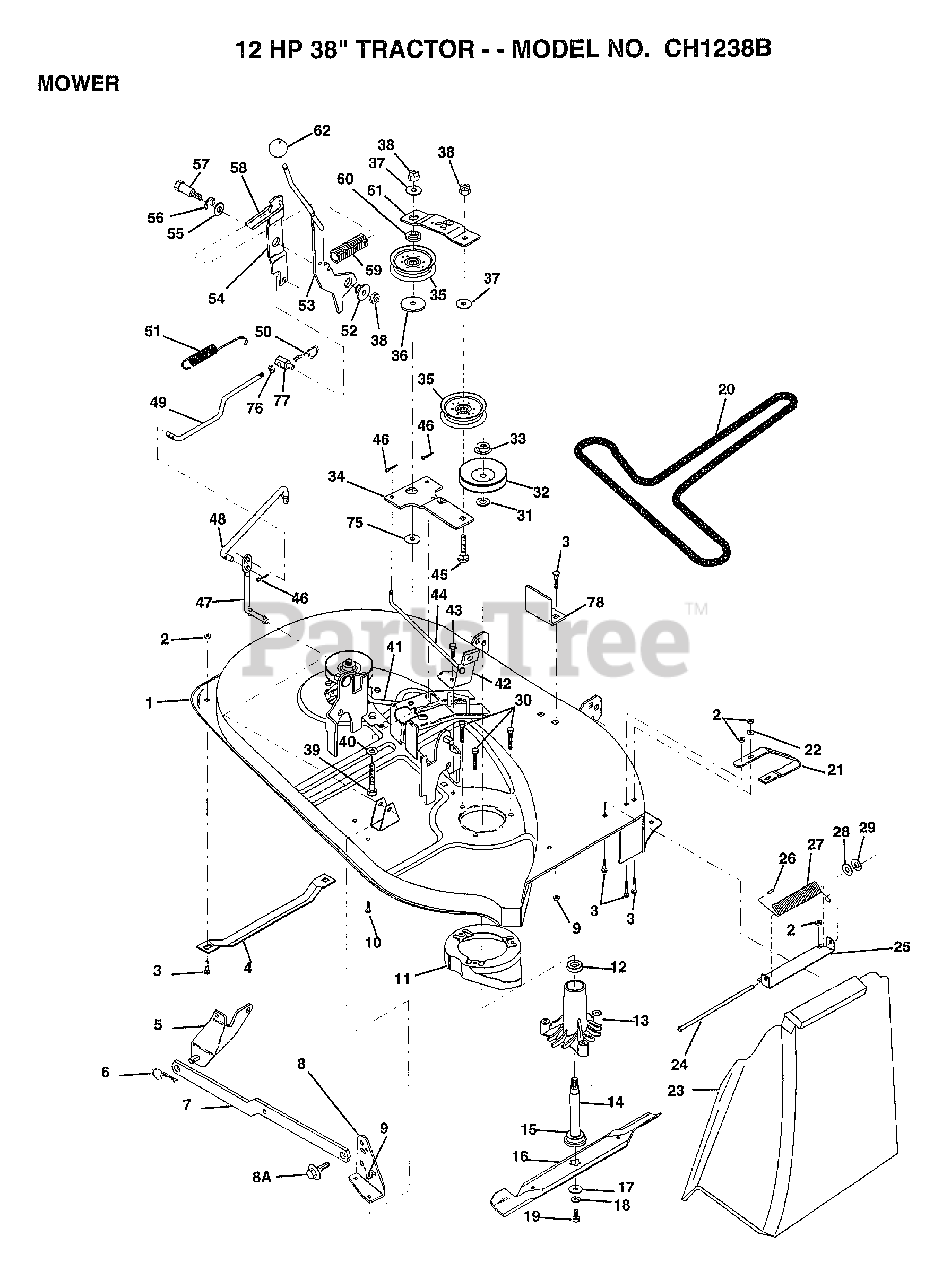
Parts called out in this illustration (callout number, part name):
2	NUT
3	BOLT
4	RUNNER-LH M
5	BRKT ASM SWAY BAR
8	BRKT DECK SW BAR
8A	BOLT SHD 5/16-18
9	NUT
10	BOLT
12	BEARING
13	HSG ASM MANDREL
15	BEARING.BALL
16	"BLADE.38""V.MULCH"
17	WASHER.HARD.BLADE
19	BLADE BOLT
20	BELT-V.88.12.MW
21	RUNNER RH
22	WASHER M
23	DEFLECTOR-SHLD T
24	ROD-HINGE T
25	BRKT DEFLECTOR
26	CAP-SLEEVE LT
27	SPRING TORSION
28	WASHER
29	NUT PUSH M
31	WASHER
34	IDLER ARM ASSY
35	FLAT IDLER PULLEY
36	SPACER RETAINER
37	WASHER GT
38	NUT
39	BOLT
40	WASHER GT
41	BRAKE ROD LH
42	BRAKE ASM
43	SCREW
44	BRAKE ROD RH
45	BOLT
47	PIVOT ROD
48	CLUTCH ROD SECOND
49	ROD CLUTCH 38/42
50	RETAINER M
51	RETURN SPRING
52	BUSHING
54	CLUTCH ARM SECOND
55	WASHER
56	RING
57	SHOULDER BOLT
58	SPRING KEEPER
60	RETAINER SPACER
61	IDLER ARM STIFF
75	HARDENED WASHER
76	NUT
77	TRUNION ADJ
78	UPSTOP DECK FT 38
